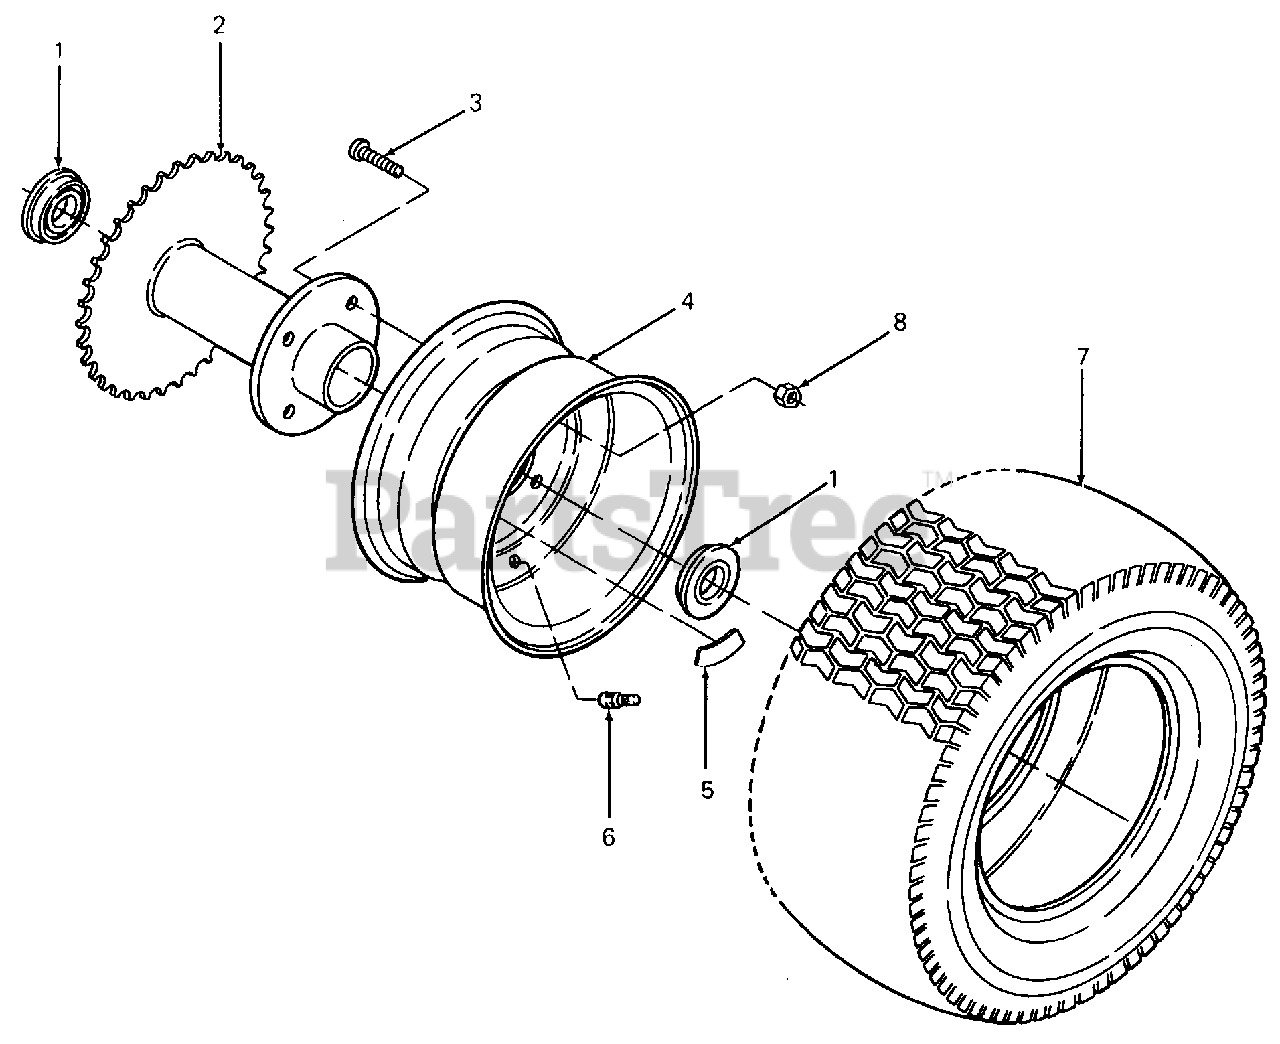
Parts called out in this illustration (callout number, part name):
1	Bearing
2	Hub Assy, Drive
3	Stud, Wheel
4	Wheel Assy w/Graphic
5	Label, Inflation
6	Valve Stem
7	Tire, 16 X 4.8/4.0 X 8
